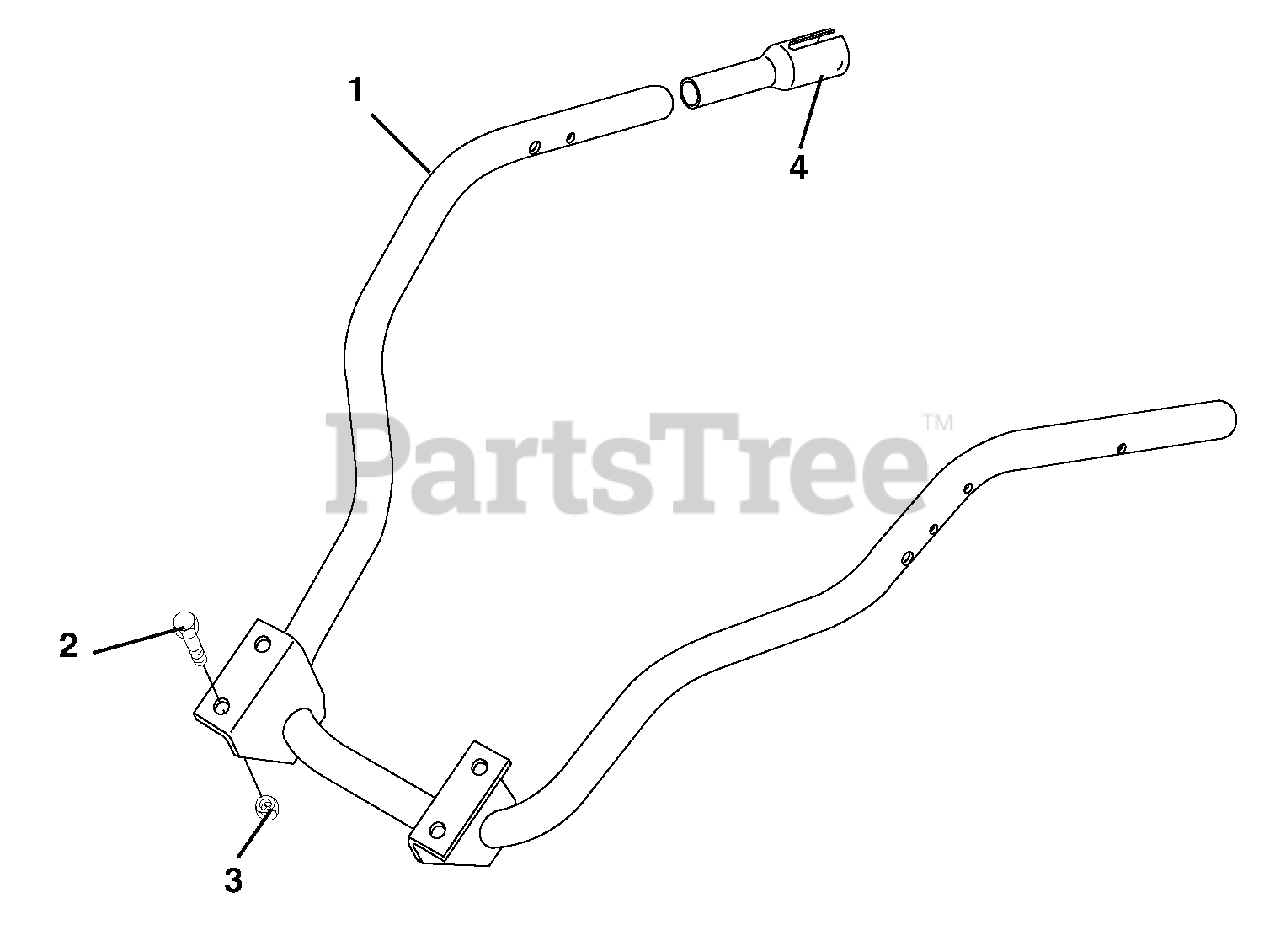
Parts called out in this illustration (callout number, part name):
1	Weldment-Handlebar
2	Bolt-Hex .38-16 x 1.25 Grade 8
3	Nut-Locking-Center .375-16
4	Insert-Handlebar
